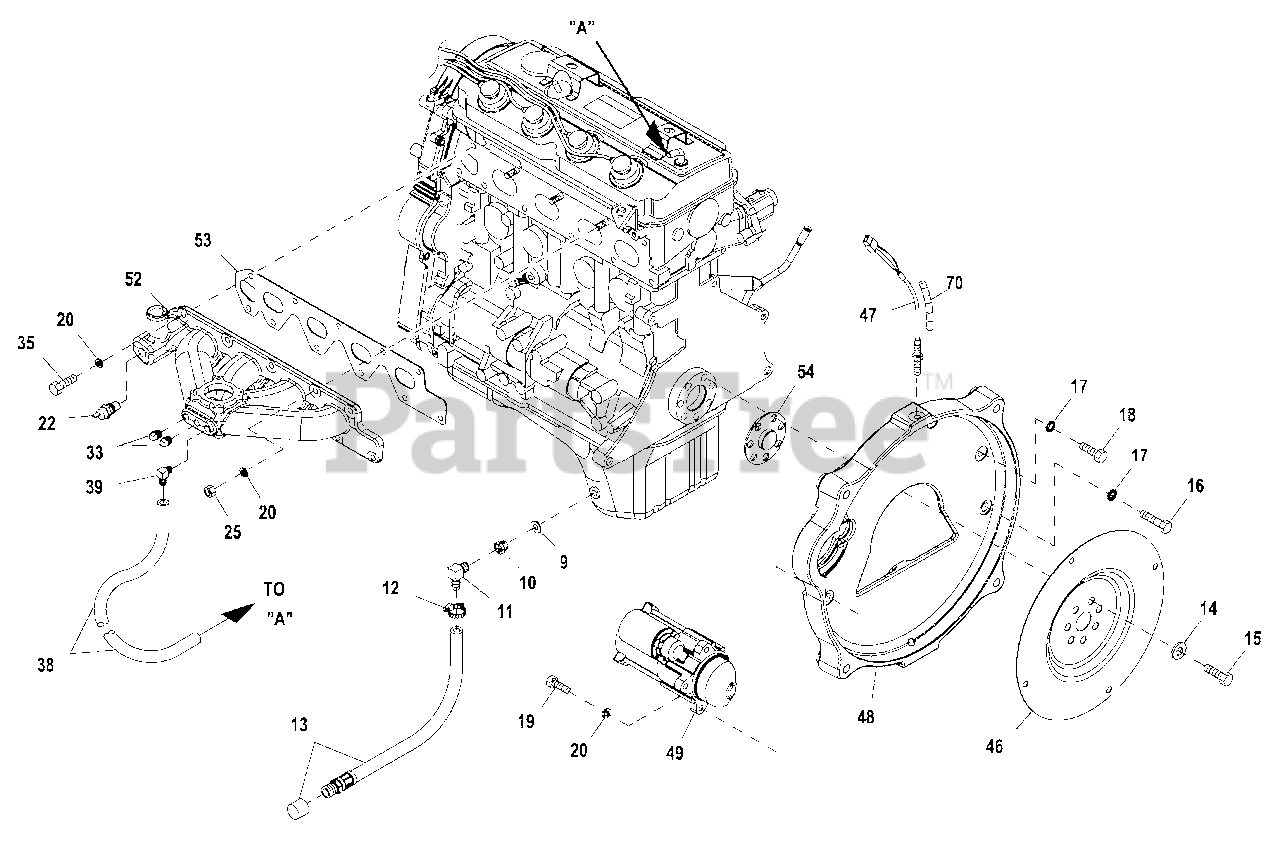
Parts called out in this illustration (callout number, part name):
1	ENGINE 2.4LG2 CERTIFIED
2	WASHER LOCK M10
3	SCREW HHC M8-1.25X35 G8.8
4	SCREW SHC M14-1.5X 35 G10.9
5	ALTERNATOR DC W/OUT PULLEY
6	SPACER DC ALTERNATOR PULLEY
7	ADAPTOR 1/8 NPTF TO 1/8 BSPT
8	HARN LOW OIL PRESS SWITCH ASSY
9	WASHER NYLON .565
10	ADAPTER M14-1.50X 3/8 NPT
11	BARBED EL 90 3/8 NPT X 3/8
12	CLAMP HOSE .38- 87
13	HOSE DRAIN ASSY 28"
14	WASHER FLAT .531 ID X 1.062 OD
15	SCREW HHC M12-1.25 X 20 G10.9
16	SCREW HHC M10-1.25X45 G8.8
17	WASHER SHAKEPROOF EXT 7/16 STL
18	SCREW HHC M10-1.25X30 G8.8
19	SCREW SHC M8-1.25 X 30 G12.9
20	WASHER LOCK M8-5/16
21	SCREW THF M6-1 X 16 N WAZ/JS
22	TEMPERATURE SENDER
23	WASHER FLAT 5/16-M8 ZINC
24	ASSEMBLY DIPSTICK G2.4L
25	NUT HEX M8-1.25 G8 CLEAR ZINC
27	ASSY DIPSTICK TUBE 2.4 G2
28	NUT HEX M10-1.25 G8YELCHR
29	SCREW SHC M8-1.25 X 25 G12.9
30	WASHER LOCK M6-1/4
31	WASHER FLAT 1/4-M6 ZINC
32	SCREW HHC M6-1.0 X 12 G8.8
33	PLUG STD PIPE 1/4 STEEL SQ HD
34	SCREW HHC M10-1.5X 120 C8.8
35	SCREW HHC M8-1.25X 25 G10.9
36	FILTER 1.5L/2.4LG2 OIL
37	COIL-2.4LG2 IGNITION
38	HOSE 3/8 ID SINGLE BRAID (15" LG)
39	BARBED EL 90 1/4 NPT X 3/8
40	SCREW HHC M8-1.25X65 C8.8
41	O-RING SIZE 9.0MM X 2.0MM NITR
42	SCREW HHC M10-1.25X 20 C8.8
43	SCREW HHM #10-32X1-1/4
44	GASKET EXHAUST MANIFOLD
45	EXHAUST MANIFOLD G2 (MACHINE)
46	FLEX PLATE 2 POLE 2.4L G2
47	ASSY MAGPICKUP(3/8-24 MALE)
48	ADAPTER ENGINE 2.4L MACHINE
49	STARTER MOTOR 12V
50	CAM SENSOR PIN ASSY
51	COVER CAM GEAR G2 REWORKED
52	MANIFOLD INTAKE (MACHINED)
53	GASKET INTAKE MANIFOLD
54	SPACER 2.4L G2 FLEX PLATE
55	SHIELD HEAT
56	SHIELD HEAT SML
57	BRACKET ASM-2.4L COIL G2
58	WASHER LOCK #10
59	ADAPTER 2.4L CRANKSHAFT MACH
60	POLY V-BELT G2
61	PULLEY DC ALTERNATOR
62	WASHER FLAT #10 ZINC
63	PLUG TAPER
64	SPARK PLUG WIRE SET 2.4L G2 IG
65	SCREW HHC M8-1.25X70 G8.8
66	CONDUIT FLEX .25"ID
67	DECAL EMISSION CTRL INFO 2.4L
68	HARN ENG G2.4LG2 NEXUS
69	TIE WRAP UL 7.4"X .19" BLK
71	NUT HEX M10-1.5 G8 YEL CHR
